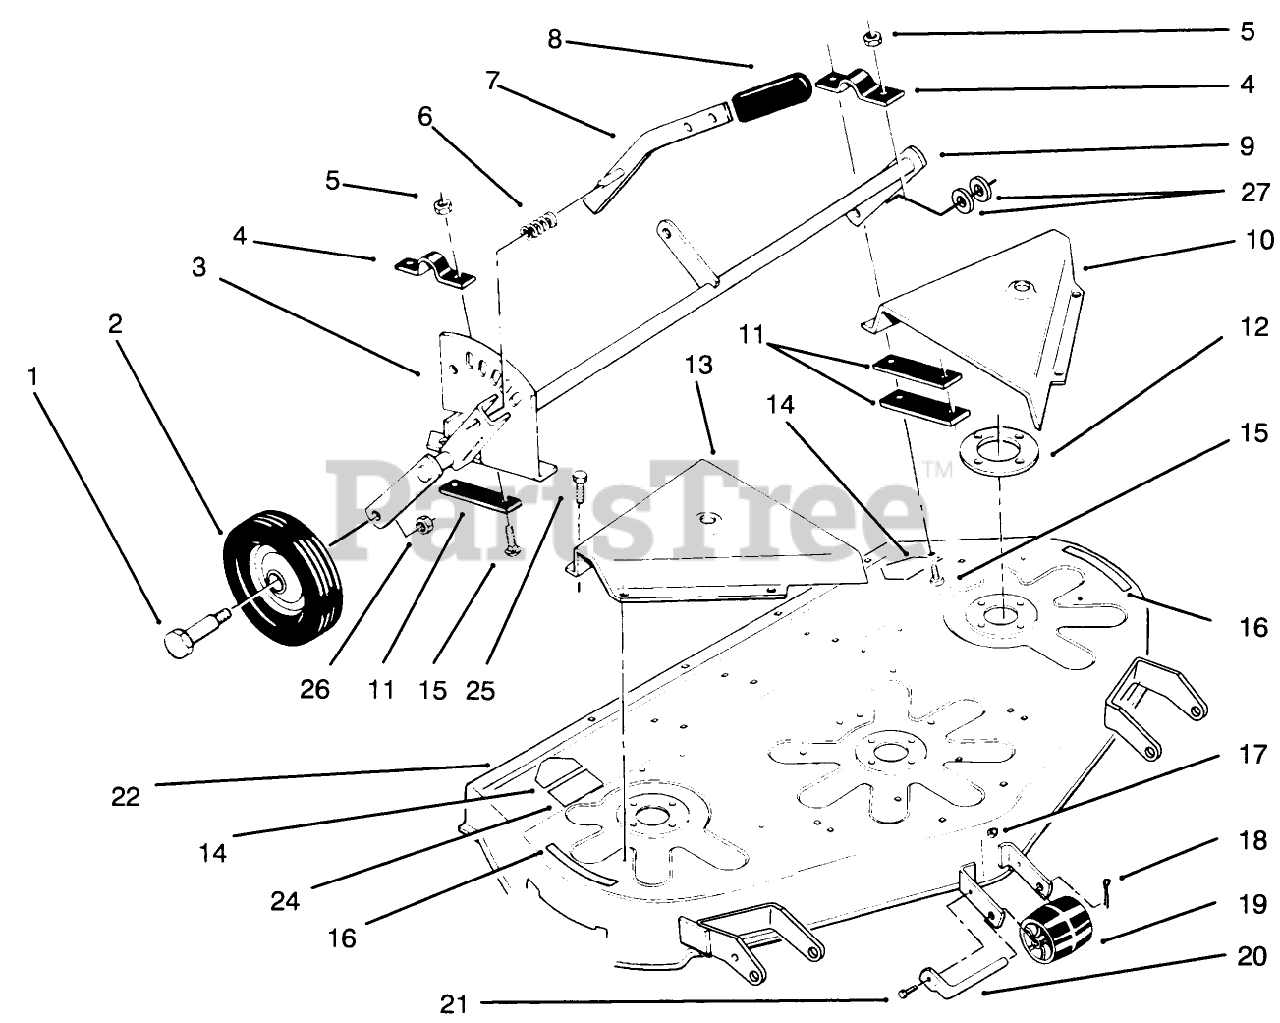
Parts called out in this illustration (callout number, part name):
1	BOLT-SHOULDER
2	WHEEL ASM
3	Quadrant
5	NUT-LOCK, NI
6	SPRING-COMPRESSION
7	Lever
9	Gauge-Wheel Support
10	Belt Cover LH
11	Bar
12	PLATE-SPINDLE
13	Belt Cover RH
14	DECAL-DANGER
15	BOLT-CARR
16	DECAL - DANGER
17	NUT-LOCK, NI
18	PIN-COTTER
19	ROLLER ASSY
20	ROLLER-SHAFT
21	SCREW-HH
22	Deck-Mower(Incl. ref.# 14 & 16)
24	DECAL-HEIGHT & BELT
25	Bolt
26	NUT-HEX
27	WASHER
